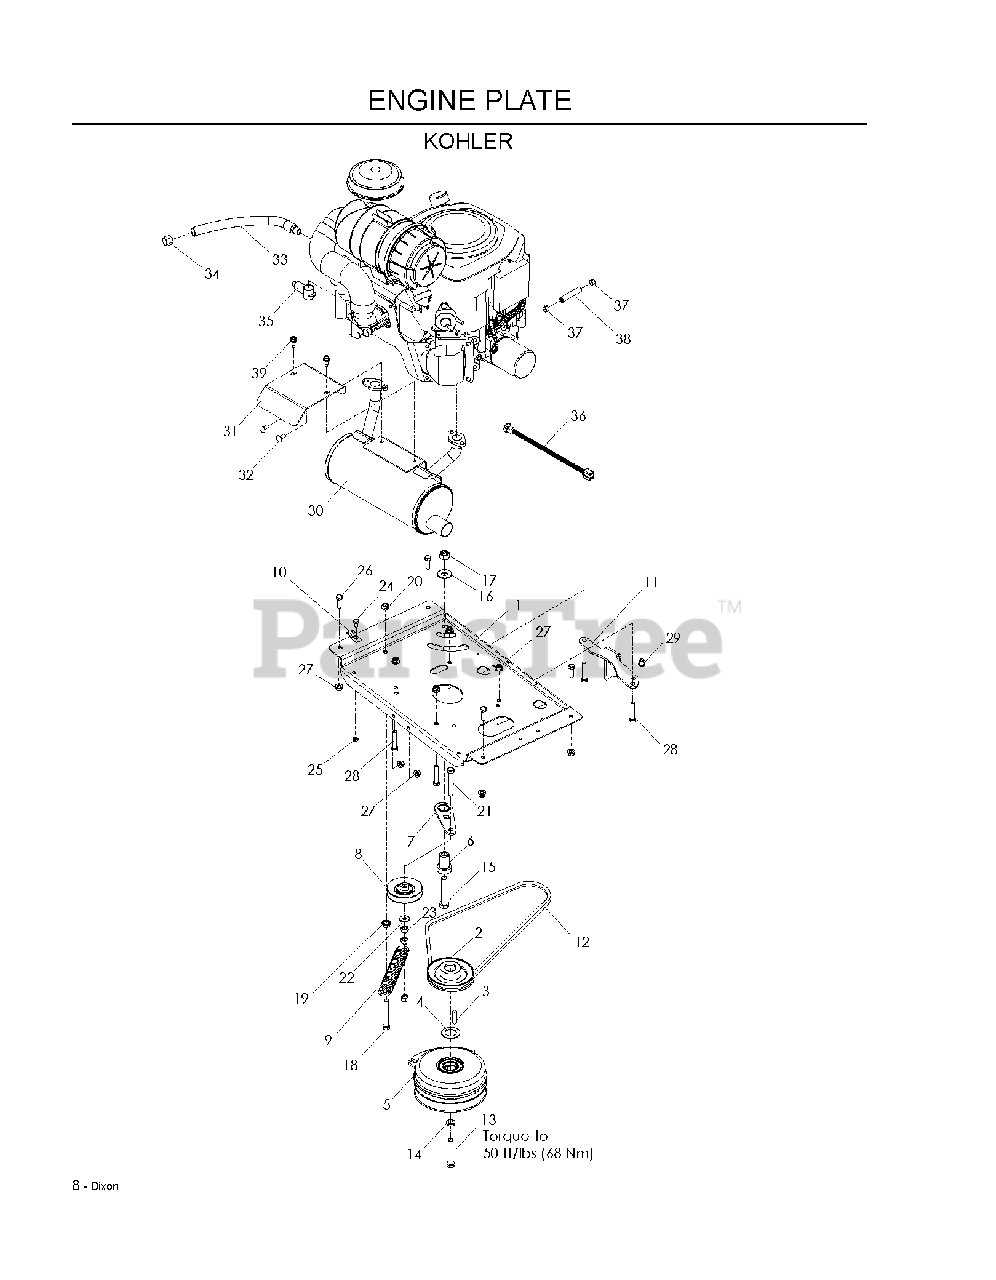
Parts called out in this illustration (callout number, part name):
1	PLATE, ENGINE, BLK
3	KEY, 1/4 SQ X 1 1/4
4	WASHER, 1.025 ID X 1.64
5	CLUTCH, 200 FT/LB
6	IDLER SPINDLE
7	IDLER ARM WELDMENT
8	PULLEY, IDLER 3 METAL
11	STOP, CLUTCH, BLK
12	BELT, "A", 44.0"
13	BOLT 7/16F X 2 1/2
14	WASHER 7/16 LOCK
15	HCS 1/2C X 2 3/4
16	WASHER 1/2 FLAT
17	NUT 1/2-13 HEX NYLOC ZD
18	SCREW 3/8C X 2 3/4 HEX CAP
19	NUT 3/8C WHIZ
20	NUT 3/8C CENTERBLOCK
21	HCS 3/8-16 X 2-1/2 TPBLT
22	WASHER 5/16 FLAT
23	NUT 3/8-16 NYLOC
24	HCS 1/4-20.
25	JAM NUT 1/4C
26	HCS 5/16C X 1
27	5/16-18 NYLOC FLANGE NUT
28	HCS 5/16C X 1 3/4
29	TIE, PLASTIC
30	Muffler, Kohler Gen II
31	MOUNT, COMMAND MUFFLER, BLK
32	BOLT 5/16C X 3/4" CARRIAGE
33	OIL DRAIN HOSE
34	DRAIN CAP
35	INSULATOR
36	HARNESS, KOHLER 10"
37	HOSE CLAMP
38	FUEL LINE 2.5"
39	BOLT 5/16-18 X 3/4
